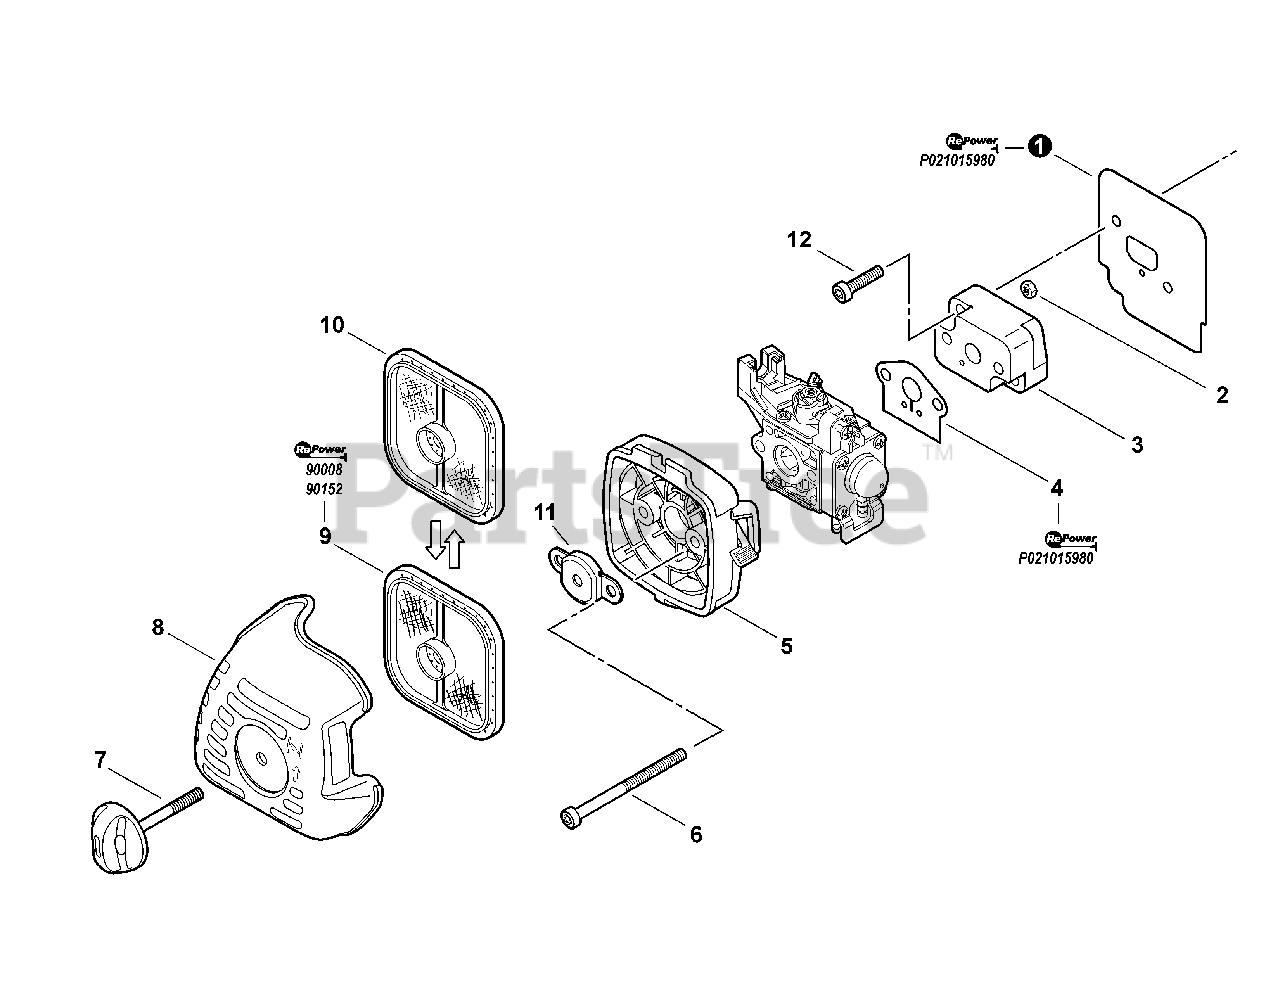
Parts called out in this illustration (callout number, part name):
1	SHIELD, INTAKE
3	INSULATOR, INTAKE
4	GASKET, INTAKE
5	CASE, AIR FILTER
6	SCREW - 5X65 -- TORX
7	THUMBSCREW
8	COVER, AIR FILTER
9	FILTER, AIR - DOUBLE LAYER
10	FILTER, AIR - SINGLE LAYER
11	PLATE, PREVENT
12	SCREW - 5X20
